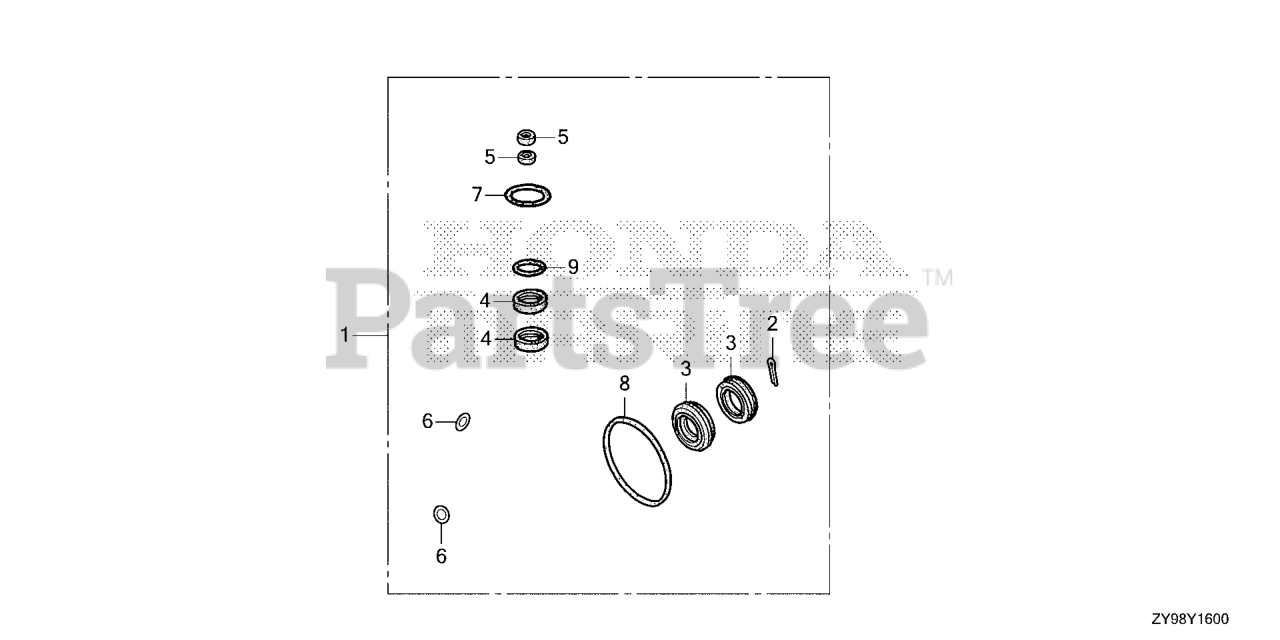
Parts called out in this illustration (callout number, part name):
1	CASE KIT, GEAR
2	PIN, SPLIT (4.0)
3	SEAL, WATER (30X45X7)
4	SEAL, WATER (23X36X6)
5	SEAL, WATER (12X21X6)
6	O-RING (6.9X1.45)
7	O-RING (49.4X3.1)
8	O-RING (94X4.1)
9	O-RING (58.5X3.5)
